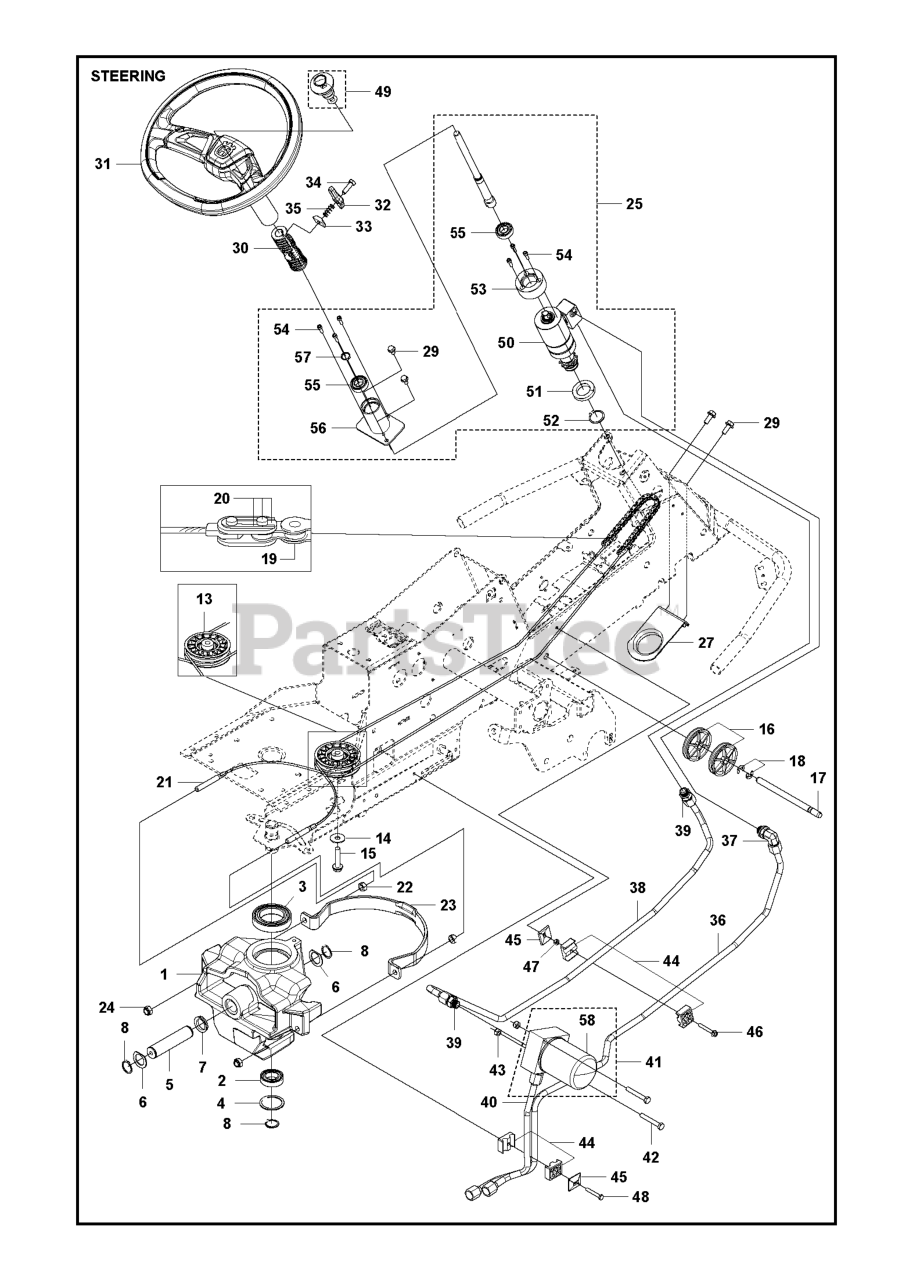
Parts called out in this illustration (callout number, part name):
2	Ball Bearing 6005-2rs
3	BALL BEARING 6010 2RS1
4	CIRCLIP SGH 47
8	RETAINING RING SGA 25
15	COLLAR SCREW
18	RETAINING RING
23	WIRE GUIDE
24	NUT
30	DRIVER STEERING WHEEL
33	FIXING PLATE
35	SPRING STEERING ADJUSTMENT
43	LOCKNUT M8
44	PIPE CLAMP
47	LOCKNUT M6
50	COMFORT STEERING
54	SCREW MC6S 6X20
55	BALL BEARING 6004-2RS1
57	RETAINING RING SGA 20
58	OIL FILTER
